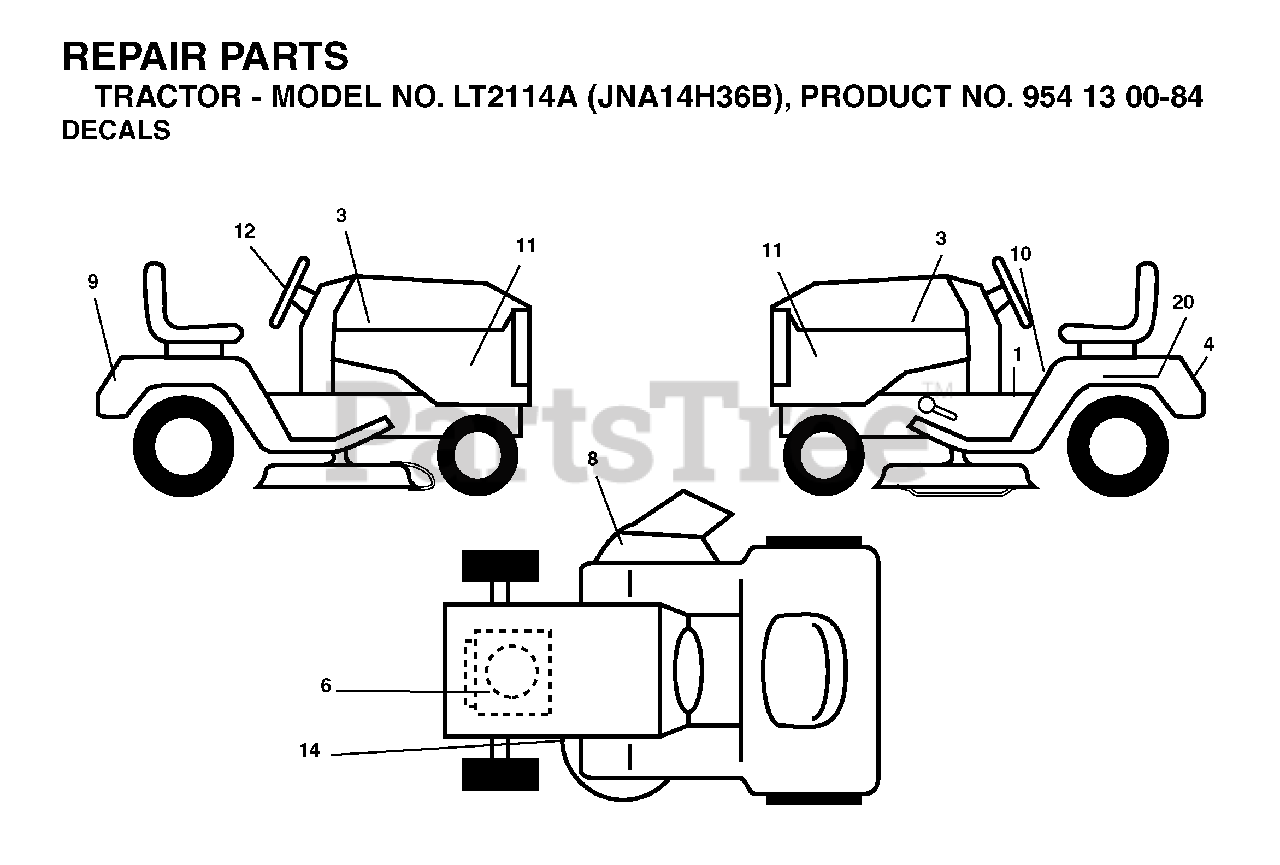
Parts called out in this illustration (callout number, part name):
1	DECAL SET
8	DECAL.WARN.KEEP.HAND.AWAY
10	DECAL FENDER DANGER
20	DECAL BTRY SYMBOLS
